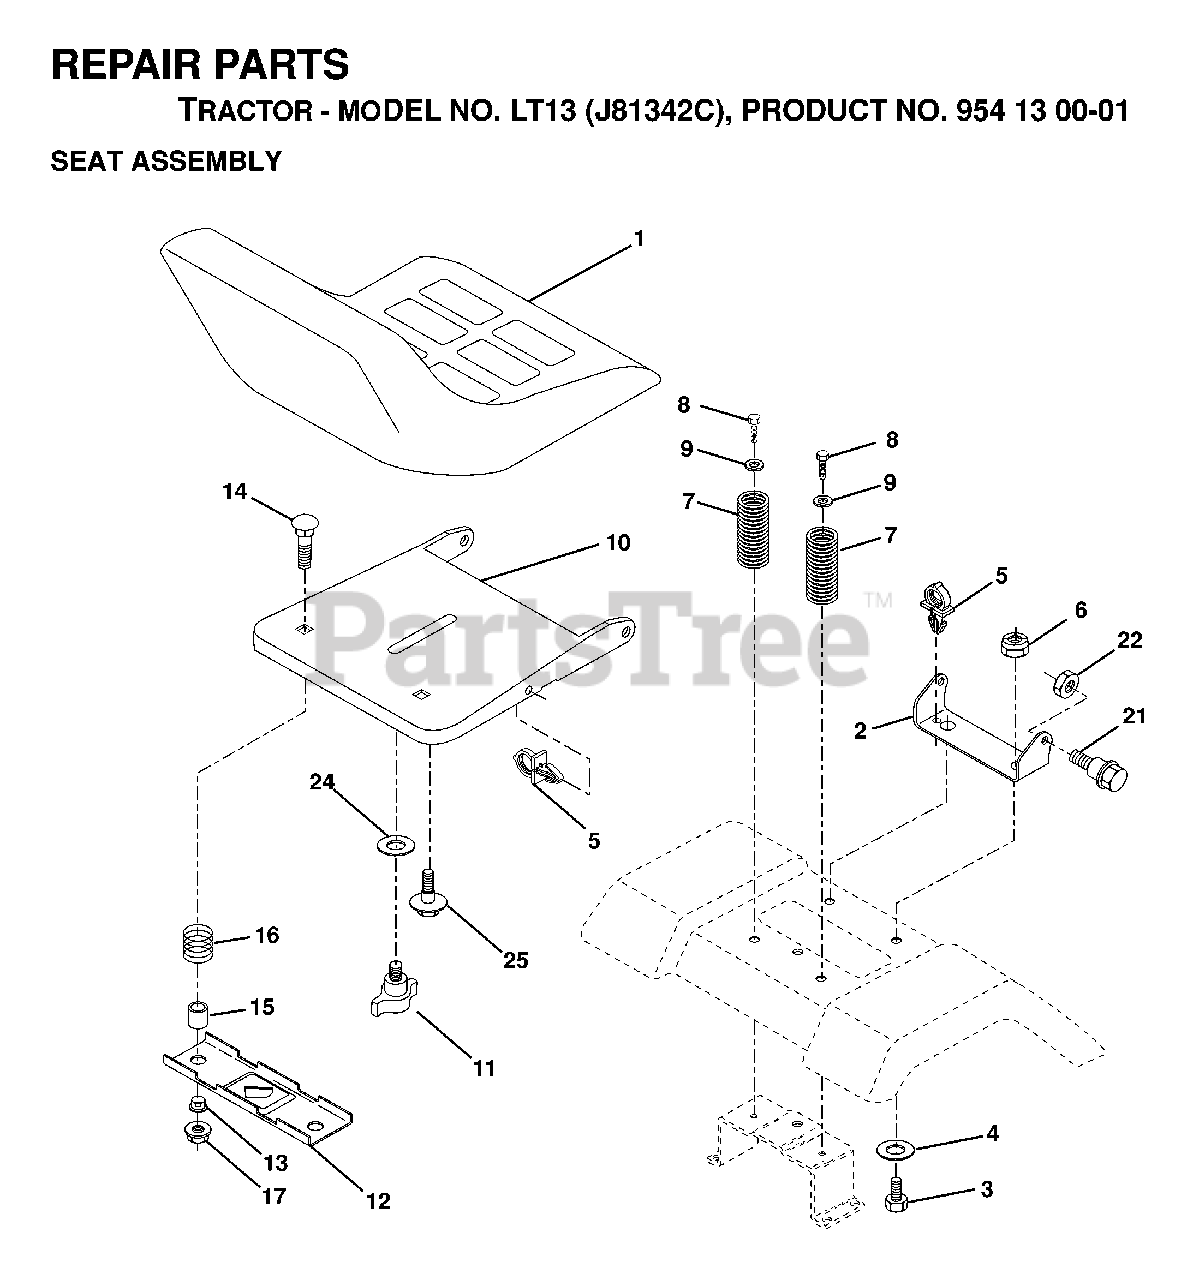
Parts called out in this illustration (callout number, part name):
2	SEAT PIVOT BRKT
3	BOLT
4	WASHER PM
5	PUSH CLIP
6	NUT
7	SPRING COMPRESSION
8	SCREW GTV
9	WASHER
10	PAN, SEAT
11	KNOB 1/2" YT
12	BRKT SWITCH
14	BOLT.ROUND.HEAD.SQUARE.NECK
15	SPACER SPLIT 28X.96
17	NUT T
21	BOLT SHOULDER 5/16-18
22	NUT.71038.31-18.HEX.NYLOCK
25	BOLT,SHOULD
